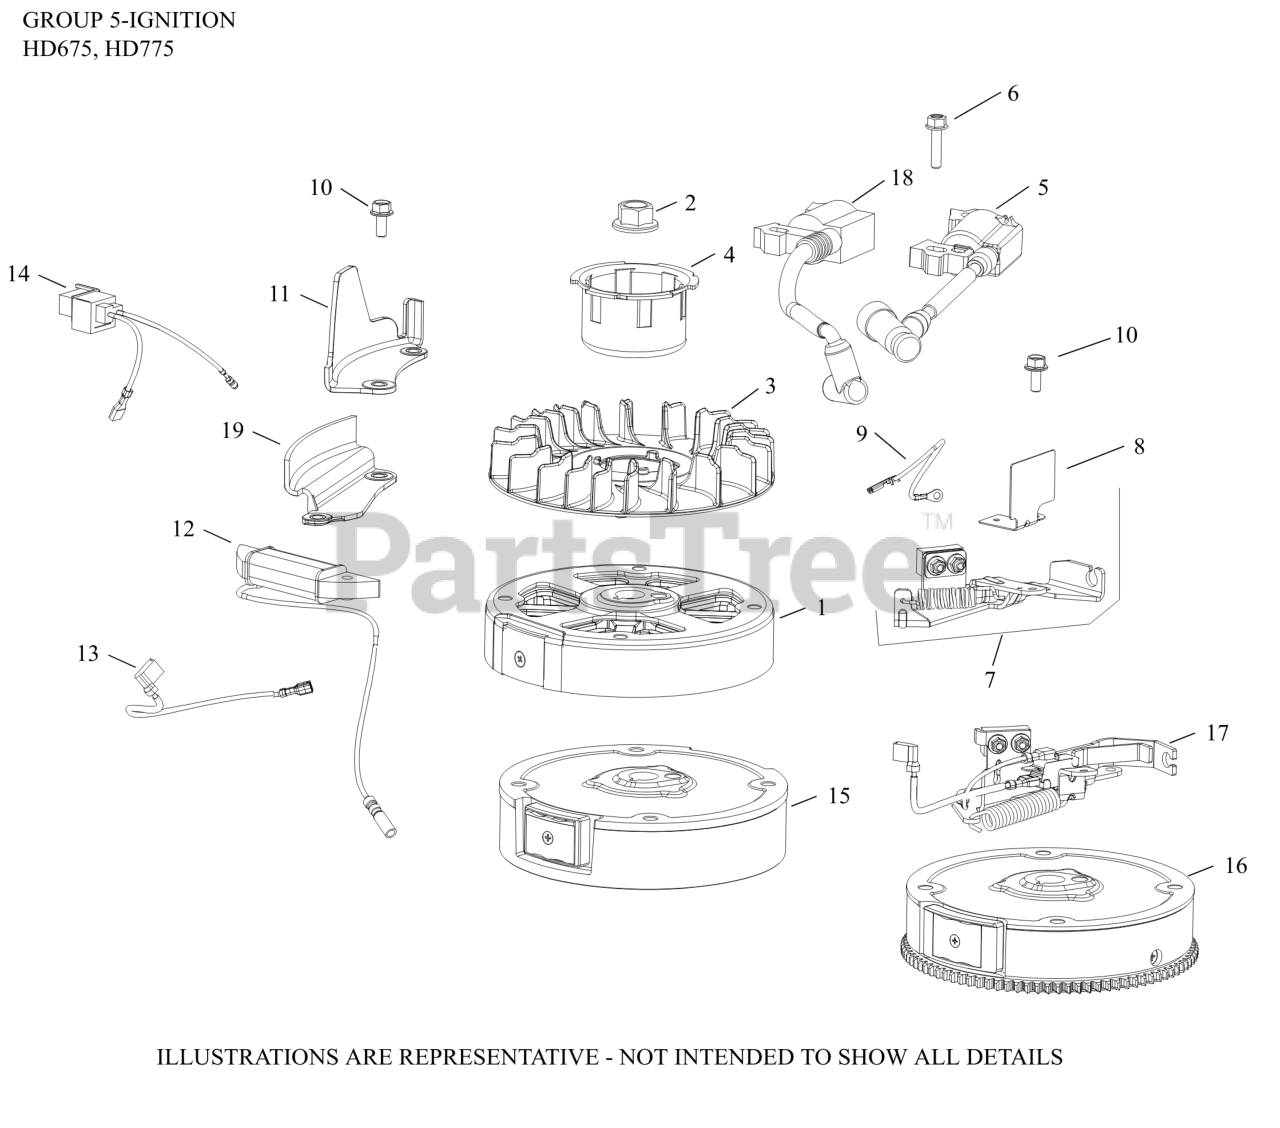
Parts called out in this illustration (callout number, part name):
2	NUT, FLYWHEEL (W/SERRATIONS)
3	FAN, FLYWHEEL
4	CUP, STARTER DRIVE
5	MODULE IGN (#1458416S)
6	SCREW, M6 X 25-(#25086436S)
6	SCREW-USE 25 086 461-S
12	STATOR ASSSEMBLY - USE 14 085 03-S
15	FLYWHEEL ASSY, ELECTRIC START
